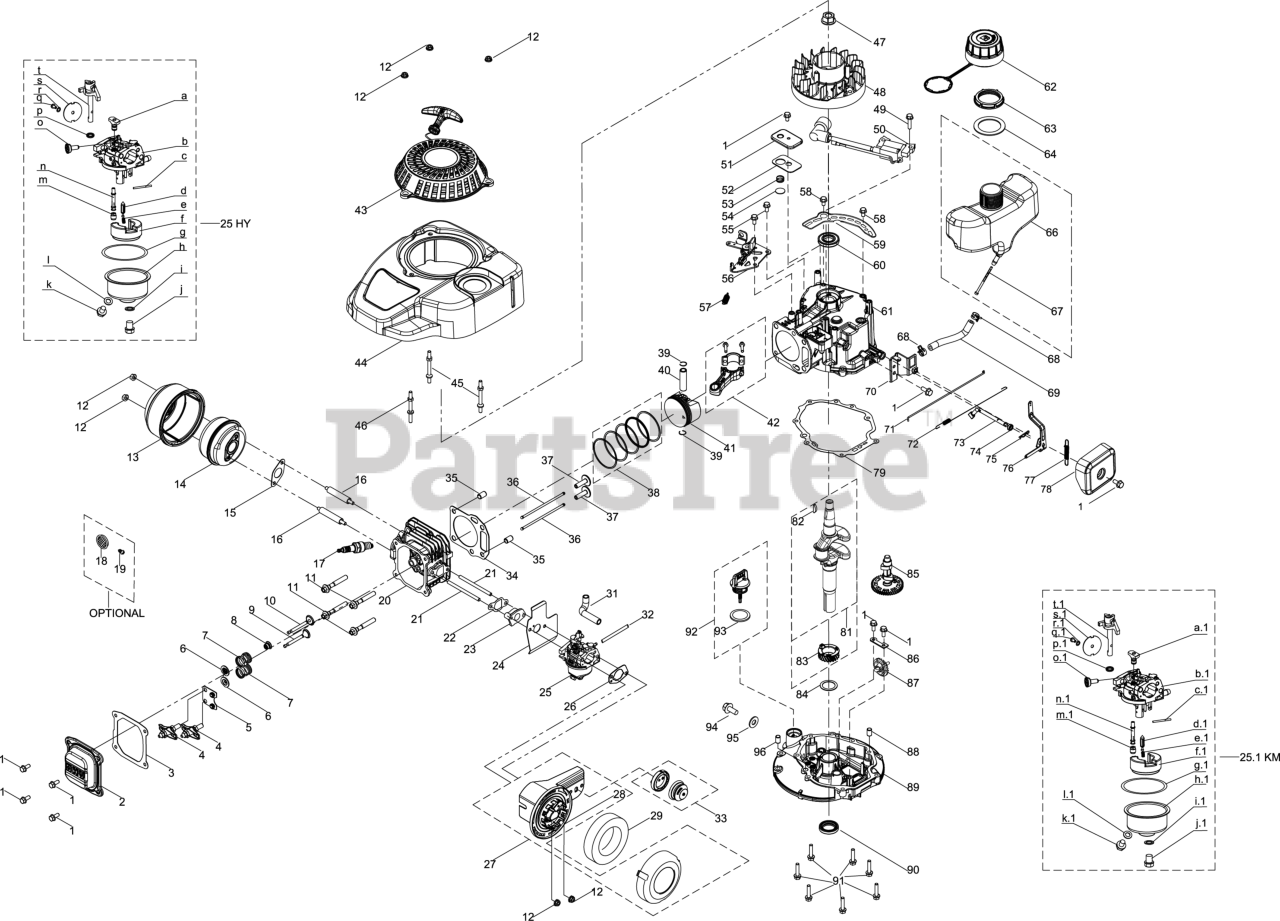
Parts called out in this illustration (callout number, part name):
1	BOLT M6-1 x 14 GR8.8
2	VALVE COVER
3	VALVE COVER GASKET
4	ROCKER ARM ASSEMBLY
5	PUSH ROD GUIDE
6	VALVE SPRING RETAINER
7	VALVE SPRING
8	INTAKE VALVE SEAL
9	EXHAUST VALVE
10	INTAKE VALVE
11	SCREW M8 x 54 GR10
13	MUFFLER SHIELD
14	MUFFLER ASSEMBLY
15	MUFFLER GASKET
16	STUD M6-1 x 76
17	SPARK PLUG
18	SPARK ARRESTOR
19	SCREW M3.5 x 9.5
20	CYLINDER HEAD
21	STUD M6 x 98
22	CARBURETOR INSULATOR GASKET
23	CARBURETOR INSULATOR
24	CARBURETOR GASKET
25	CARBURETOR
25.1	CARBURETOR
26	AIR FILTER BASE GASKET
27	AIR FILTER ASSEMBLY
28	AIR FILTER BASE
29	FOAM AIR FILTER
31	BREATHER HOSE
32	PRIMER HOSE
33	VENTED PRIMER ASSEMBLY
34	CYLINDER HEAD GASKET
36	PUSH ROD
37	TAPPET (LIFTER)
38	PISTON RING SET
39	SNAP RING-PISTON PIN
40	PISTON PIN
41	PISTON
42	CONNECTING ROD ASSEMBLY
43	STARTER RECOIL ASSEMBLY
44	ENGINE SHROUD ASSEMBLY
45	STUD M6 x 75
46	STUD M6 x 73
47	FLYWHEEL NUT
48	FLYWHEEL
49	BOLT M6-1 x 25 GR8.8
50	IGNITION COIL ASSEMBLY
51	BREATHER COVER PLATE
52	BREATHER COVER GASKET
53	BREATHER VALVE SPRING
54	BREATHER VALVE
55	BOLT M6-1 x 12 GR8.8
56	ENGINE BRAKE ASSEMBLY
57	BRAKE SPRING
58	BOLT M6-1 x 10 GR8.8
59	SHROUD COVER PLATE
60	UPPER CRANKSHAFT SEAL
62	FUEL CAP W/TETHER
63	FUEL TANK NUT
64	FUEL TANK UPPER GROMMET
66	FUEL TANK
67	FUEL FILTER
68	CARBURETOR HOSE CLAMP
70	COMPONENT BRACKET
71	THROTTLE LINKAGE
72	THROTTLE LINKAGE SPRING
73	GOVERNOR ARM SHAFT
75	COTTER PIN
76	GOVERNOR ARM ASSEMBLY
77	GOVERNOR SPRING
78	GOVERNOR SHIELD
79	CRANKCASE COVER GASKET
81	Crankshaft Assembly
82	WOODRUFF KEY
84	THRUST WASHER
85	CAMSHAFT
86	GOVERNOR GEAR MOUNTING PLATE
87	GEAR GOVERNOR
88	DOWEL PIN 9 X 14
89	CRANKCASE COVER
90	LOWER CRANKSHAFT SEAL
91	BOLT-M6-1 x 28 GR8.8
92	DIPSTICK ASSEMBLY
93	DIPSTICK O-RING
94	OIL DRAIN PLUG
95	WASHER
96	DOWEL PIN 9 X 14
